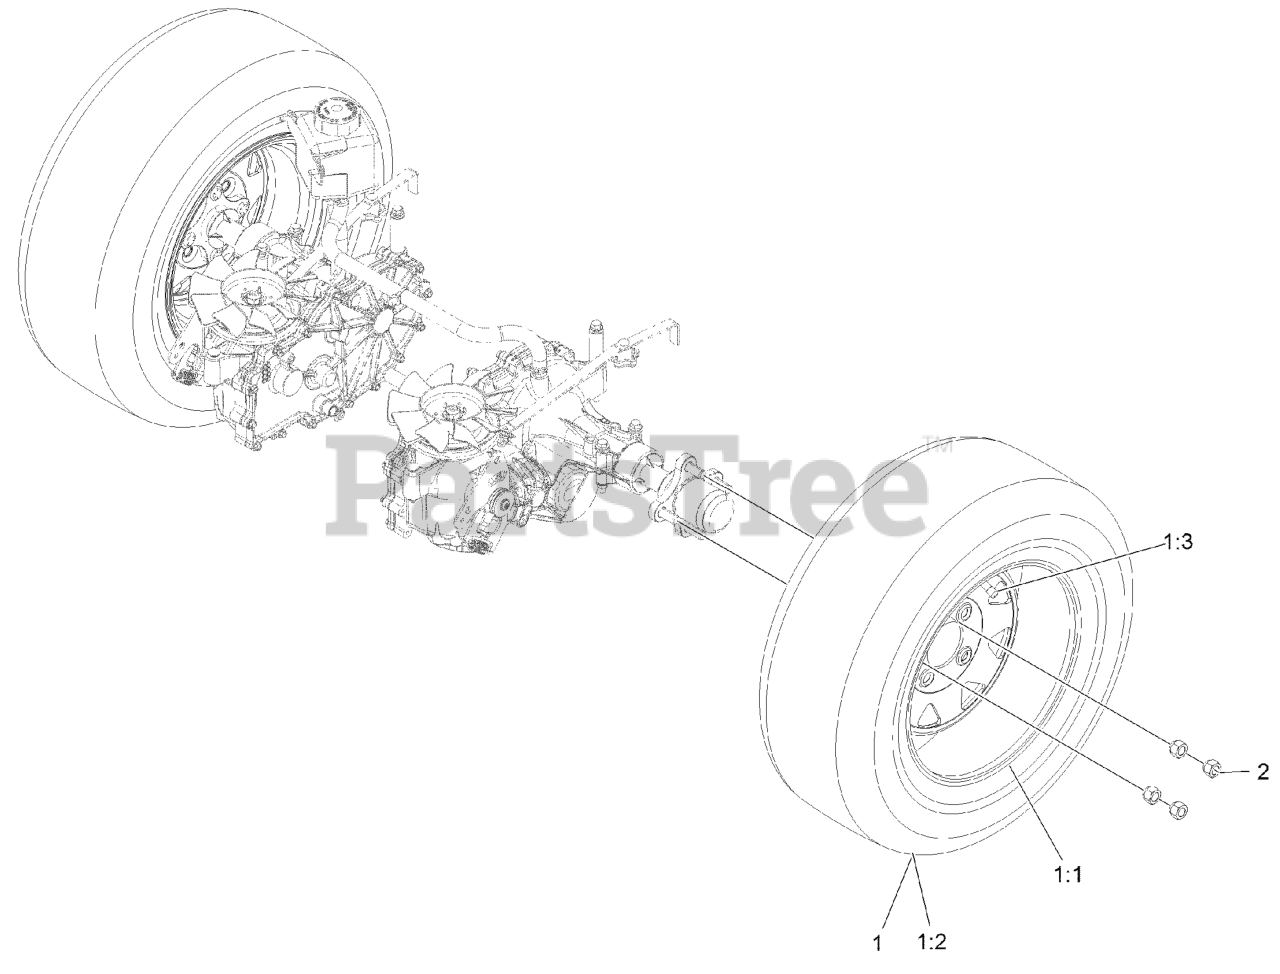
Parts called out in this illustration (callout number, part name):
1	WHEEL AND TIRE ASM
1:3	Stem-Valve
2	NUT-LUG
